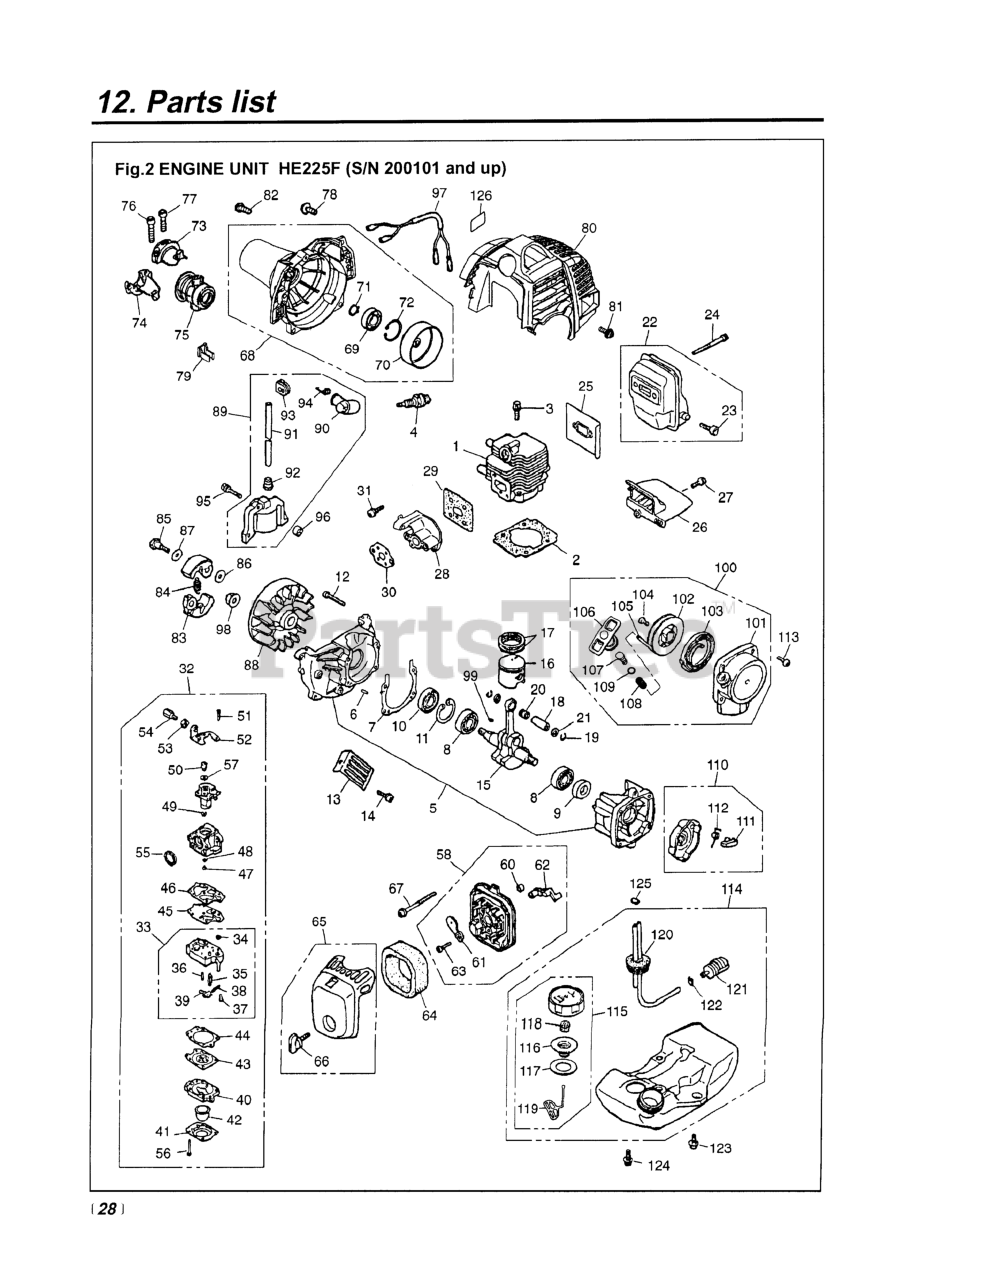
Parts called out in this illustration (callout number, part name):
1	CYLINDER
2	GASKET, BASE (RPLS -12212)
3	BOLT, M5 X 22
5	CRANKCASE
6	PIN
7	GASKET (RPLS -21140)
8	BEARING
9	SEAL, OIL (RPLS 1100-21210)
10	SEAL, OIL (RPLS 1140-21220)
11	RING, SNAP, M28 x 1.2
12	BOLT, M5 X 30
14	SCREW,M5 X 14 (RPLS 1400-15510
15	CRANKSHAFT (RPLS 1850-42000)
16	PISTON (REPLACES 1140-41110)
17	RING, PISTON (RPLS 1850-41210)
18	PIN, PISTON 5x8x26
19	RING, SNAP (RPLS 1101-41320)
20	BEARING (RPLS 1140-41330)
21	WASHER
22	MUFFER ASSEMBLY
23	ARRESTER (RPLS 5850-15140)
24	BOLT, M5 x 50
25	GASKET
26	PLATE, MUFFLER (RPLS -15220)
27	SCREW, M4 X 16
28	INSULATOR
29	GASKET (RPLS -13120)
30	GASKET (REPLACES -13130)
31	SCREW, M5X20 (RPLS.1400-75510)
32	CARBURETOR
33	BODY, PUMP
35	VALVE, INLET
36	SPRING, METERING LEVER
37	SCREW, METERING LEVER PIN
38	PIN, METERING LEVER
39	LEVER
40	BODY, PURGE
41	COVER, PUMP
42	PUMP, PRIMING
43	DIAPHRAGM (USE 4810-81260)
44	GASKET, DIAPHRAGM
45	DIAPHRAGM
46	GASKET, PUMP
47	JET
48	RING, O
49	RING
50	SWIVEL
51	SCREW
53	NUT, CABLE ADJUSTER
54	SCREW, CABLE ADJUSTER
55	RING, PACKING
56	SCREW
57	WASHER
58	BODY ASSEMBLY
60	SLEEVE
61	PLATE, CHOKE
62	LEVER, CHOKE
63	SCREW (REPLACES 50030272)
64	ELEMENT
65	COVER ASSEMBLY
66	KNOB (RPLS -82220)
67	SCREW, M5 x 60
68	HOUSING ASSY.
70	DRUM, CLUTCH
71	RING, SNAP (RPLS 3130-13270)
72	RING, SNAP, M28 x 1.2
73	BRACKET (A) (RPLS -31211)
74	BRACKET (B)
75	CUSHION (RPLS -31231)
76	BOLT, M5 X 22
77	BOLT, M5 X 10
78	SCREW, M5X20 (RPLS.1400-75510)
79	CLAMP
80	COVER, ENGINE (USE -32111)
81	SCREW (RPLS-32161)
82	SCREW,M5 X 14 (RPLS 1400-15510
83	SHOE (RPLS 1100-51114)
84	SPRING
85	BOLT
86	WASHER, FLAT (USE 182303)
88	ROTOR
89	COIL-A (USE T1700-71201)
90	CAP
91	CORD
92	CAP
93	GROMMET
94	SPRING
95	BOLT
96	SPACER
97	CORD COMP
99	KEY
100	RECOIL ASSEMBLY
101	CASE
102	REEL
103	SPRING, SPIRAL
104	SCREW (RPLS -75150)
105	ROPE
106	KNOB
107	COLLAR
108	SPRING
109	WASHER
110	PULLEY ASSY (RPLS -75210)
111	RATCHET (RPLS 1850-75220)
112	SPRING, RETURN
113	SCREW (RPLS-32161)
114	TANK ASSY (RPLS -85000)
115	CAP ASSY (RPLS. 5601-85201)
116	HOLDER - A (RPLS 5601-85230)
117	PACKING
118	FILTER
119	STOPPER
120	PIPE COMPLETE
121	FILTER (RPLS 1850-85300)
122	CLIP (REPLACES 2841-31280)
123	SCREW W/ WASHER
124	SCREW
125	CLIP
126	LABEL
